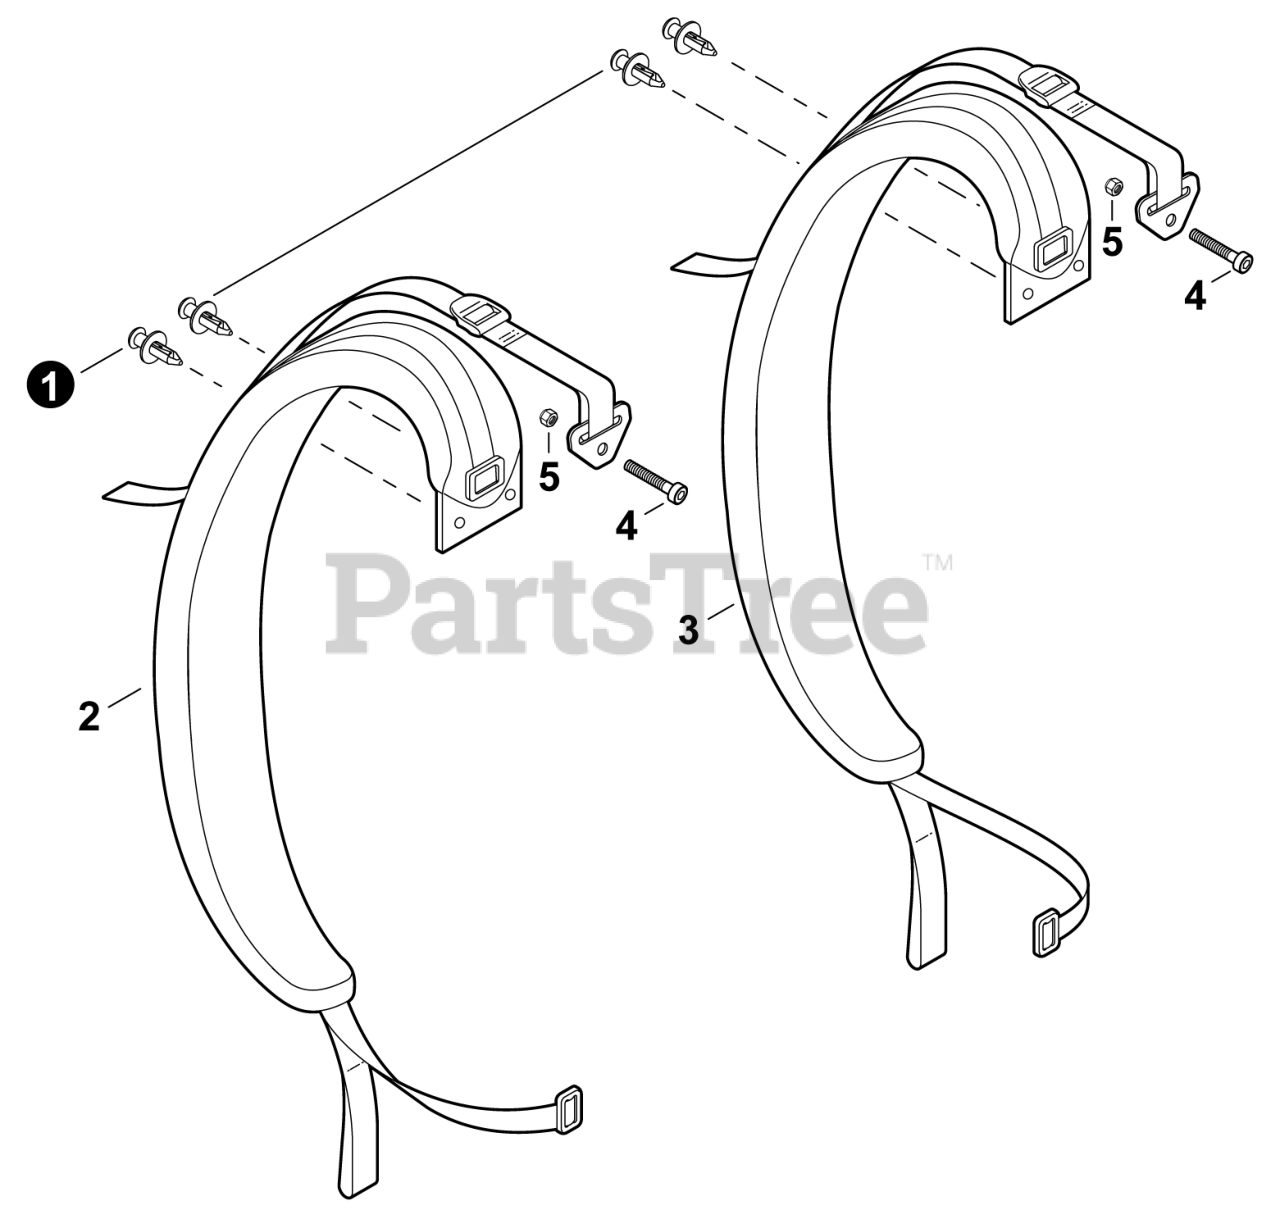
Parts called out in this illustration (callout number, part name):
2	SHOULDER STRAP - LEFT
3	SHOULDER STRAP - RIGHT
4	BOLT, TORX 5×30
5	NUT, LOCK M5
